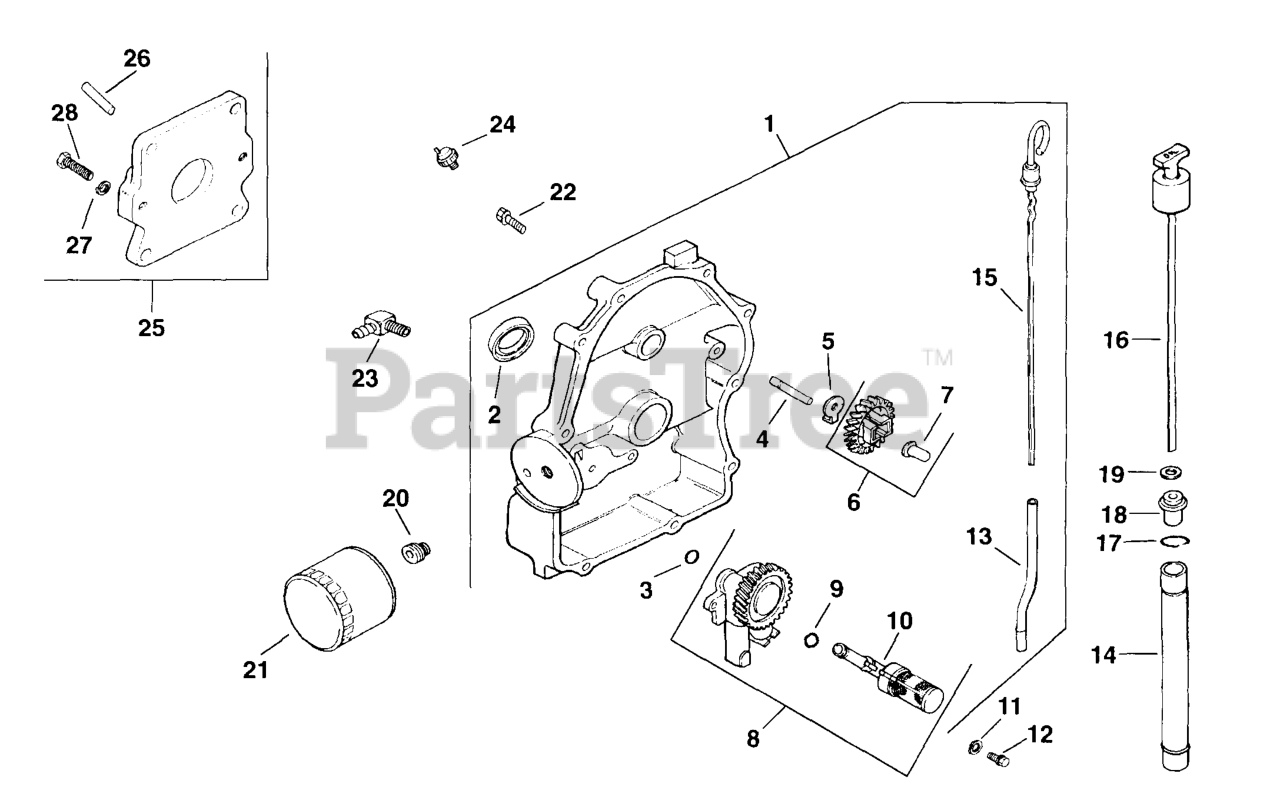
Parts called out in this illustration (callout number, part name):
1	Plate Assembly, Closure
2	Seal, Oil (Pto End)
4	Shaft, Governor Gear
5	Tab, Locking
6	Kit, Governor Gear W/Pin
7	Pin, Governor Regulating
8	Oil Pump Assembly
10	Pick-Up, Oil
11	Washer, Plain 6 Mm
12	Screw, Hex. Flange M6x1.0x25
13	Tube, Dipstick (Bent Tube)
15	Dipstick
20	Nipple, Oil Filter
21	Filter, Oil
22	Screw, Hex. Flange M8x1.25x46
23	Connector, Hose 90ø 1/4"
24	Switch, Oil Pressure
